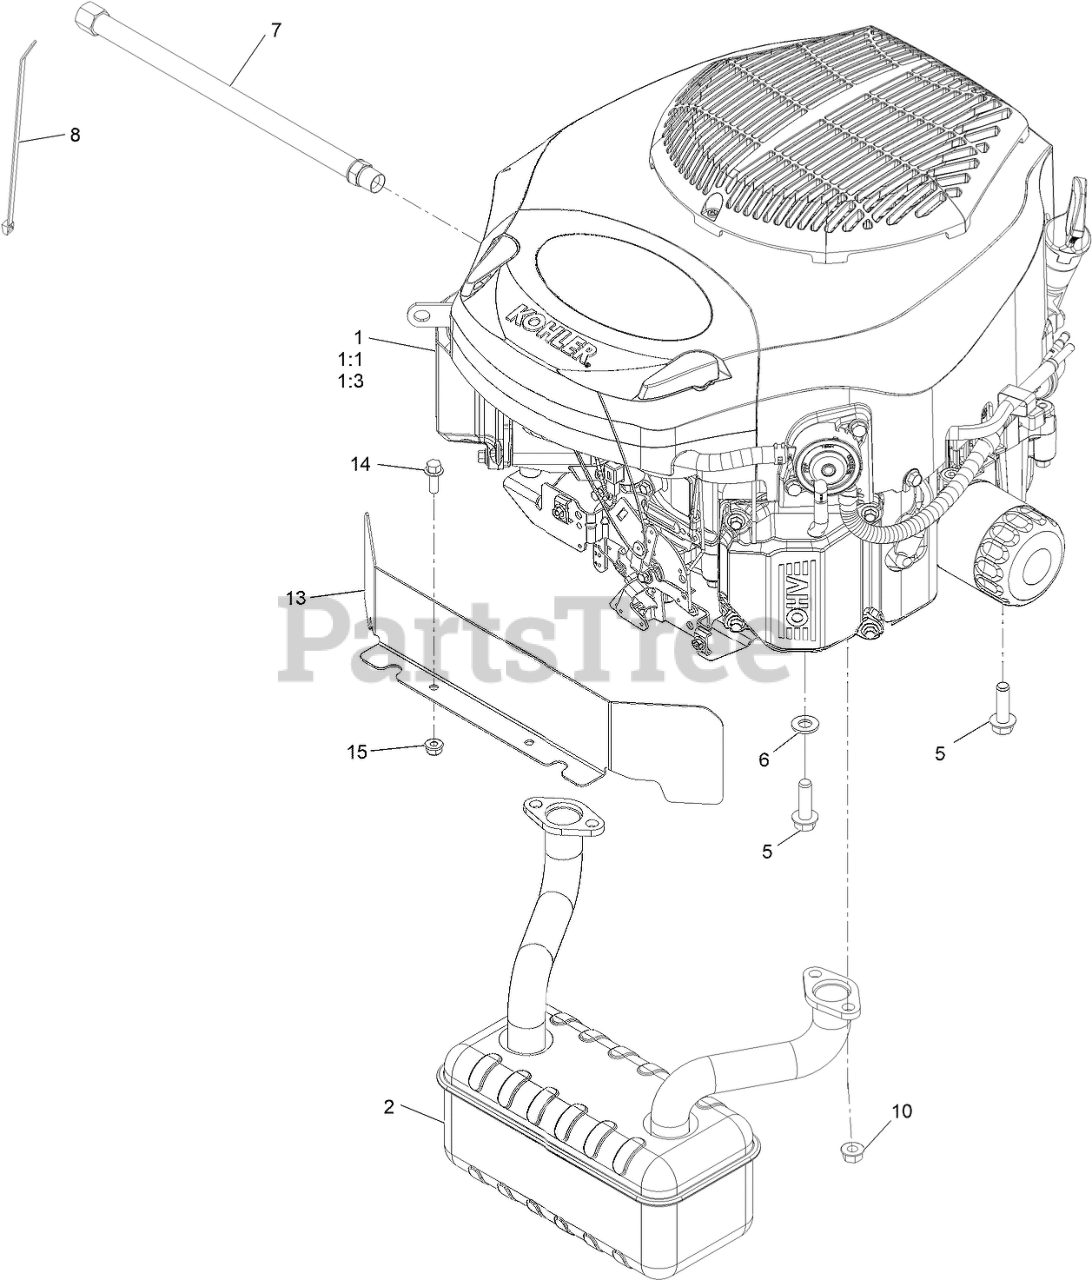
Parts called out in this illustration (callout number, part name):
2	MUFFLER
5	SCREW-THD
6	WASHER-FLAT
7	HOSE-DRAIN, OIL
8	TIE-CABLE
10	NUT-HF
13	SHIELD-HEAT
14	SCREW-HHF
15	NUT-FLANGE, NI
